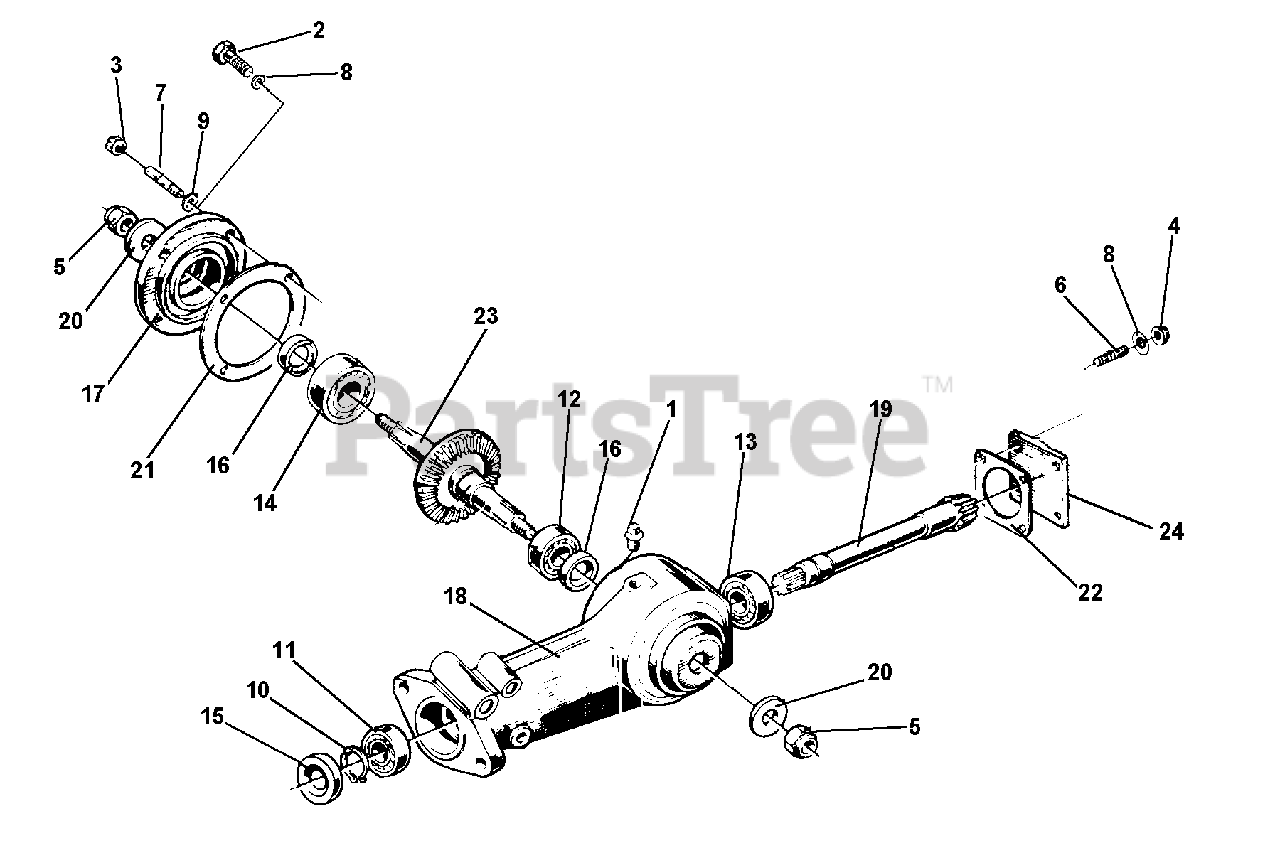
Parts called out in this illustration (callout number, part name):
2	SCREW M8 X 25
3	NUT, SELF LOCKING M8
5	NUT, SELF LOCKING M14 STANDARD
6	SUTD M8 X 32 X 14 X 14
7	STUD M8 X 38 X 14 X 14
8	SUPER WASHER 8 DIN
9	WASHER, LOCK M8.4
10	CIRCLIP EXTERN. D 20
11	BEARING 20 X42 X 12 6004
12	BEARING 25 X 52 X 15 6205
13	BEARING 20 X 47 X 14 7204 B
15	OIL SEAL 20 X 42 X 7 STANDARD
18	ROTARY HOE CENTRAL ASSEMBLY
19	PINION SHAFT, EXTENDED
22	ROTARY HOE GASKET
23	SHAFT WITH GEAR
24	REAR COVER FOR ROTARY HOE
